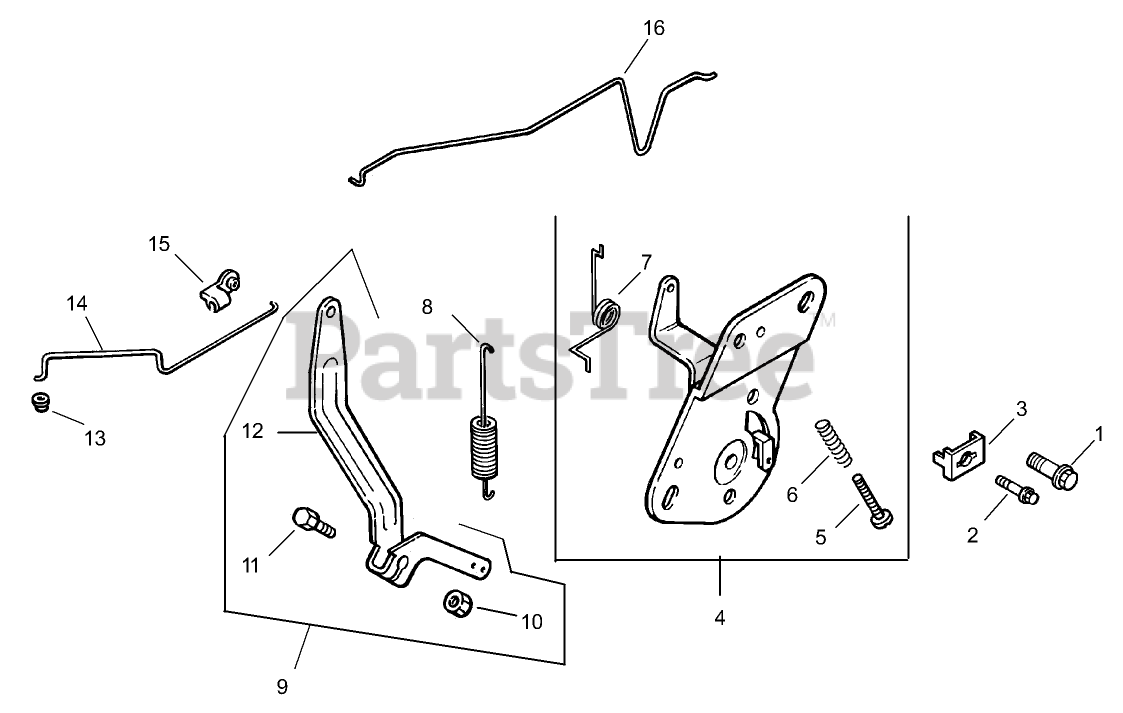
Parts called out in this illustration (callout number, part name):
1	Screw-Socket, 6 Lobed (Thread Forming, M6x1.0x20)
2	SCREW-FLANGE, THREAD FORMING (M5X0.8X16)
3	CLAMP-CABLE
4	Control, speed assembly (Incl. Ref. #5-7)
5	Screw-Pan Head (w/loctite)
6	Spring-Control, Speed
7	Spring-Return, Choke
8	Spring-Governor
9	Kit, governor lever (Incl. Ref. #10-12)
10	Nut-Flange, Hex (1/4-20)
11	Bolt-Square Neck, Round Head (1/4-20x1)
12	Lever-Governor
13	BUSHING-LINKAGE, THROTTLE
14	Linkage-Throttle
15	BUSHING-RETAINING, LINKAGE
16	Linkage-Choke
